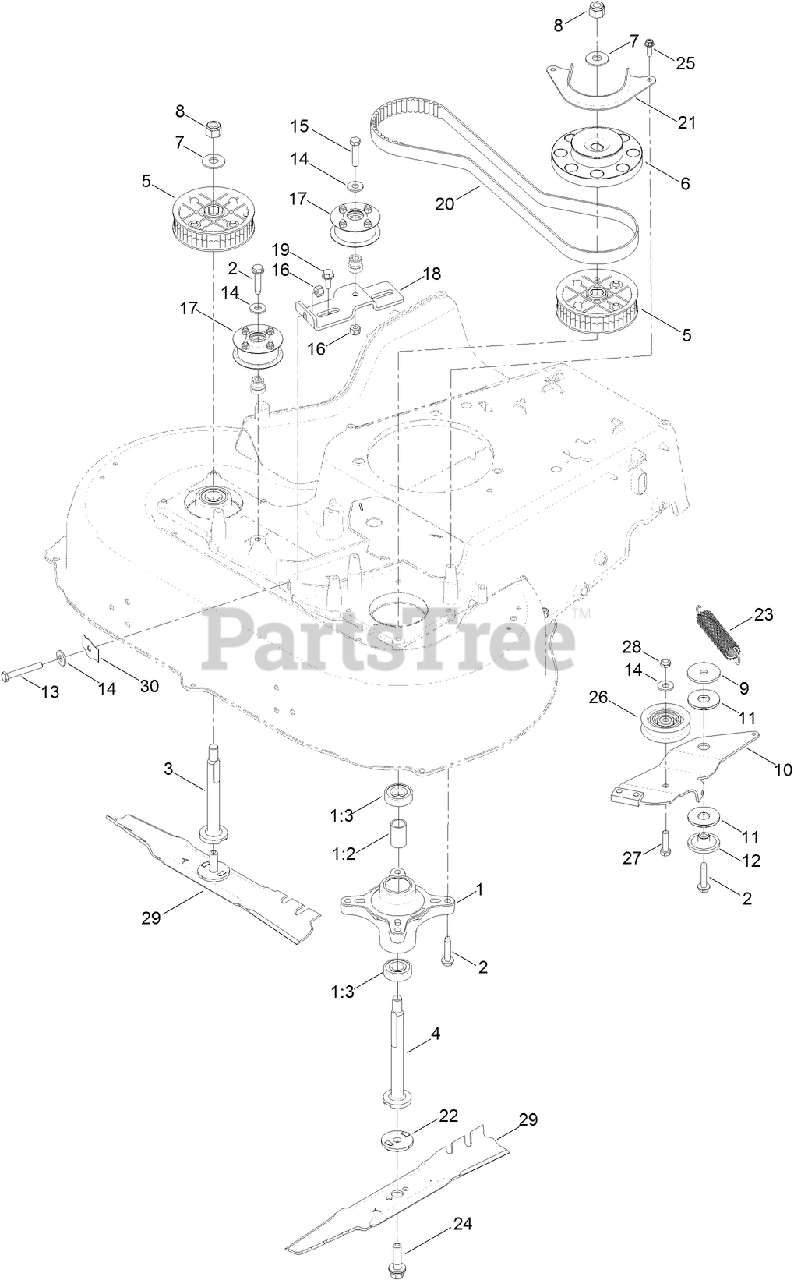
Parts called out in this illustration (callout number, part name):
1:2	SPACER
1:3	BEARING-BALL
3	SHAFT-SPINDLE
4	SHAFT-SPINDLE
5	SPROCKET
6	PULLEY-BRAKE, SPINDLE
7	WASHER-SPRING
8	NUT-HEX
9	WASHER-REBOUND
10	ARM-BRAKE
11	WASHER-FRICTION, COMPOSITE
13	BOLT-TAP, HH
14	WASHER-FLAT
15	SCREW-HH
16	NUT-LOCK, NI
17	PULLEY KIT
18	BRACKET-IDLER
19	SCREW-SHOULDER,HWH
20	BELT-SYNCHRONOUS
21	GUIDE-BELT, SPINDLE
22	ADAPTER-BLADE
23	SPRING-EXTENSION, BRAKE
24	BOLT-BLADE
25	SCREW-HWHTF
26	PULLEY-IDLER
27	SCREW-HH
28	NUT-LOCK, NI
29	BLADE-ROTARY
30	SPRING-FLAT
